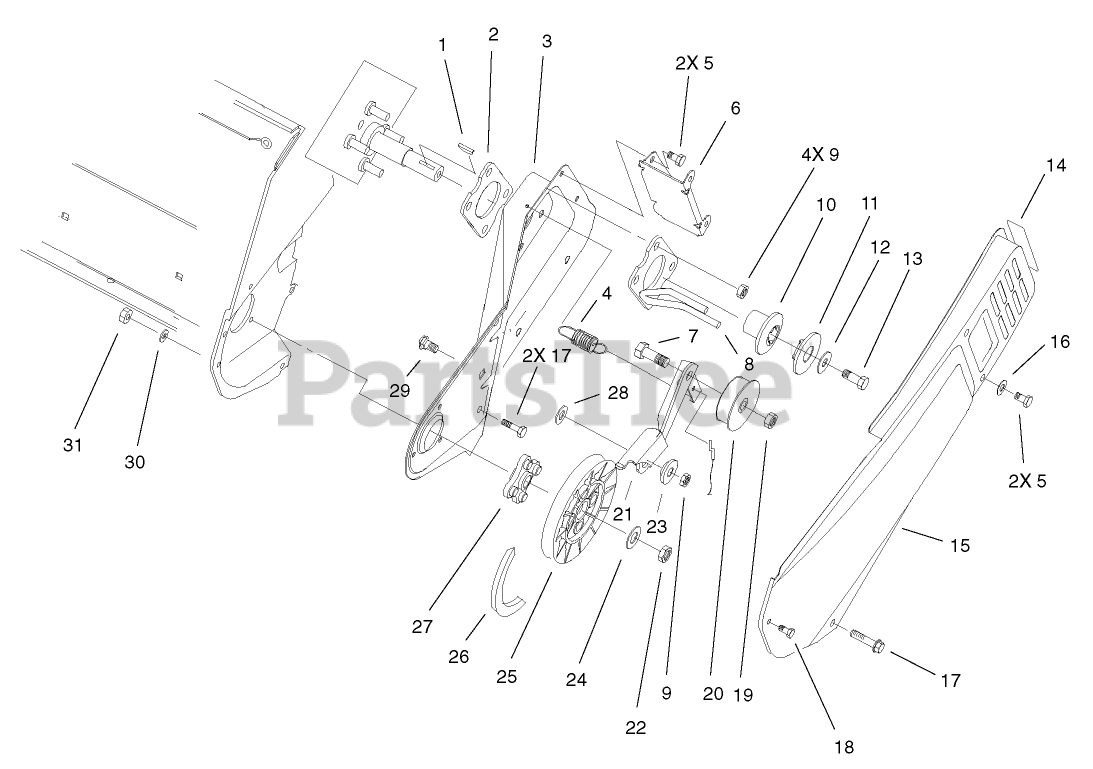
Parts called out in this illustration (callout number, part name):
1	KEY-WOODRUFF
2	PLATE-ENGINE
3	SIDEPLATE-LH
4	SPRING-BRAKE
5	SCREW-HWH
6	BRACKET-COVER, BELT
7	SCREW-HH
8	GUIDE-BELT
9	NUT-LOCK, NI
10	HUB-HALF SHEAVE
11	CAP-HALF SHEAVE
12	WASHER-FLAT
13	SCREW-HH
14	DECAL-HOT
15	COVER-BELT
16	WASHER-FLAT
17	SCREW-PLASTIC
20	PULLEY-IDLER
21	ARM-BRAKE
22	NUT-LOCK, NI
23	BUSHING-IDLER
24	WASHER-FLAT
25	PULLEY-DRIVEN
26	V BELT
28	WASHER
29	SCREW-CARR
30	WASHER-FLAT
31	NUT-LOCK, NI
